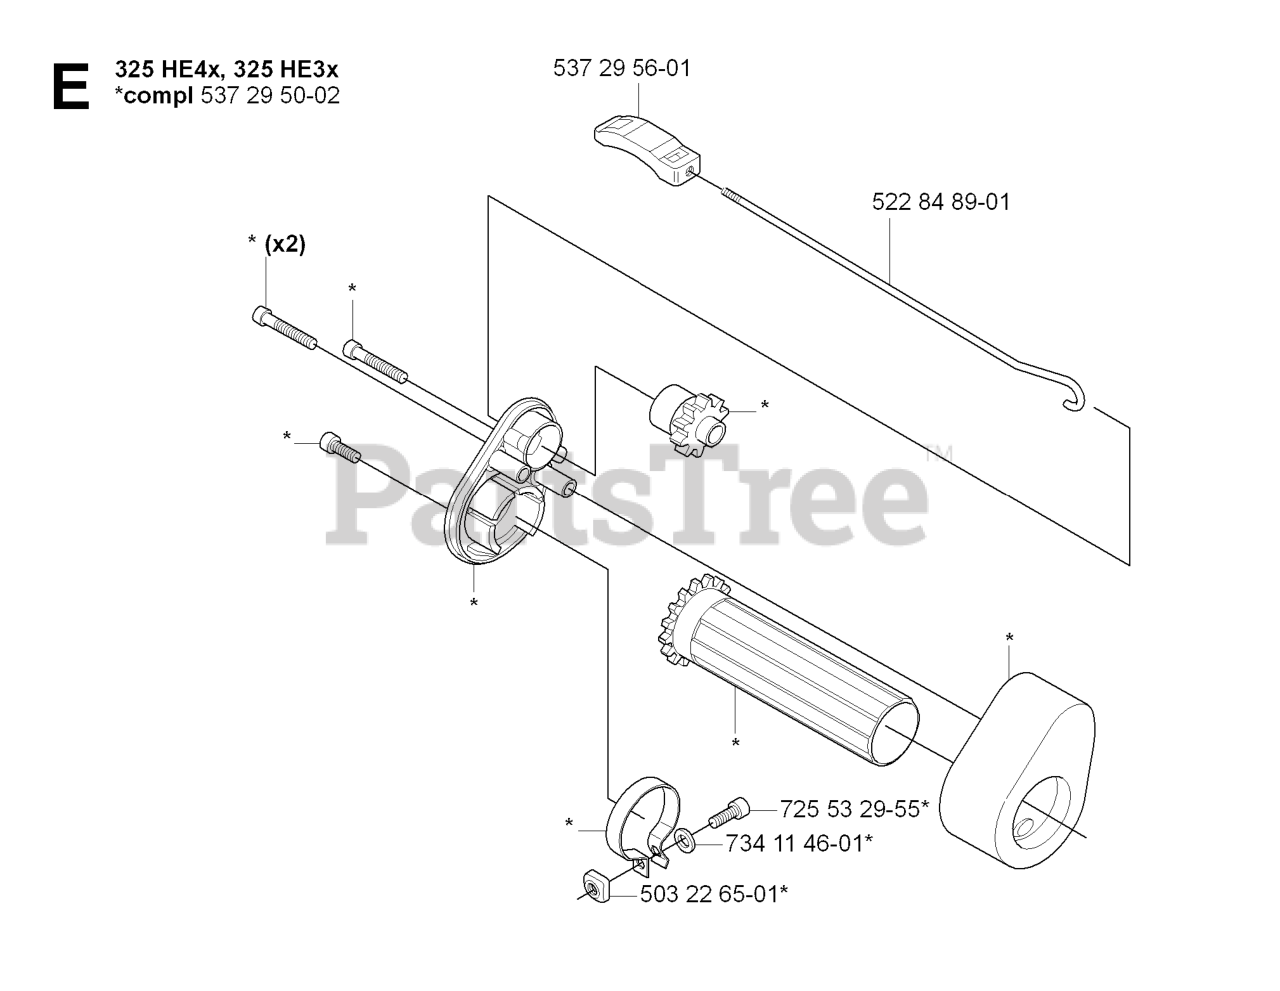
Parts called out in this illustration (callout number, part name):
1	RP.DECAL.BADGE.170MM.TEXTLOGO
2	DECAL,ETHANOL E85 WARNING
3	DECAL, WARNING SPARK ARRESTOR
4	DECAL.SHIELD.TN.DRT17.HUSQ
5	DECAL TI (2 2)
6	DECAL.SHIFT.INDICATOR.DRT
7	DECAL.REVERSE.HUSQ.TILLER
9	DECAL.DRT.WARN.ENG/F
12	DECAL.FOWARD.HUSQ.TILLER
